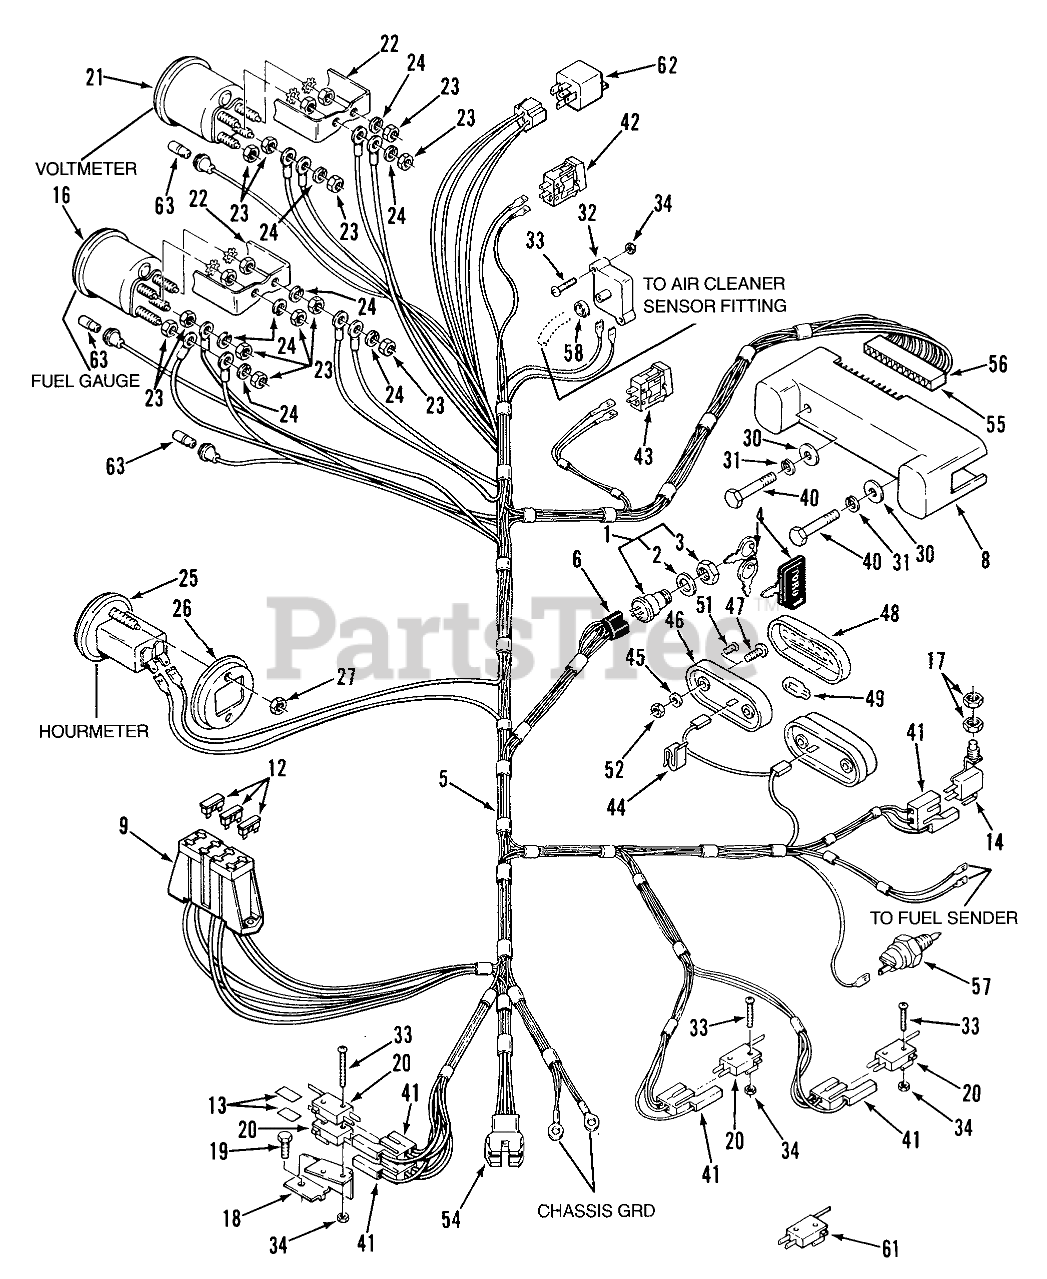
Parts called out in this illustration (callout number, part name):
1	IGNITION SWITCH ASM
2	Washer
4	Ignition Key
5	MAIN-HARNESS & DIA
6	CONNECTOR-5 WAY-SERV
8	6-Light Circuit Module
9	FUSE-HOLDER 4 WAY
12	FUSE-10 AMP
13	BARRIER - SWITCH
14	Seat Switch
16	Fuel Gauge (Includes item 22)
17	NUT-HEX, SPECIAL
18	Support-Switch
19	Bolt
20	SWITCH
21	Voltmeter (Includes item 22)
22	BRKT-GAUGE MOUNTING
23	Nut
24	Lockwasher
25	Hourmeter (Includes item 26)
26	BRKT-GAUGE MOUNTING
27	Hex Nut
30	WASHER
31	LOCKWASHER
32	SENSOR-AIR CLEANER
33	Screw
34	NUT HEX 4-40 ELAST
40	SCREW
41	CONNECTOR BODY
42	Light Switch
43	SWITCH-TEST
44	SPEED CLIP
45	Lockwasher
46	BASE-TAIL LIGHT
47	Screw
48	LENS-TAIL LIGHT
49	LIGHT BULB
51	RIVET-4
52	Nut
54	9-CIRCUIT CAP
55	Connector-Male
56	Terminal
57	SENSOR-HYDRO OIL HOT
58	CLAMP-HOSE 5/16"
61	SWITCH - CLUTCH
62	RELAY
63	LAMP-MINIATURE
